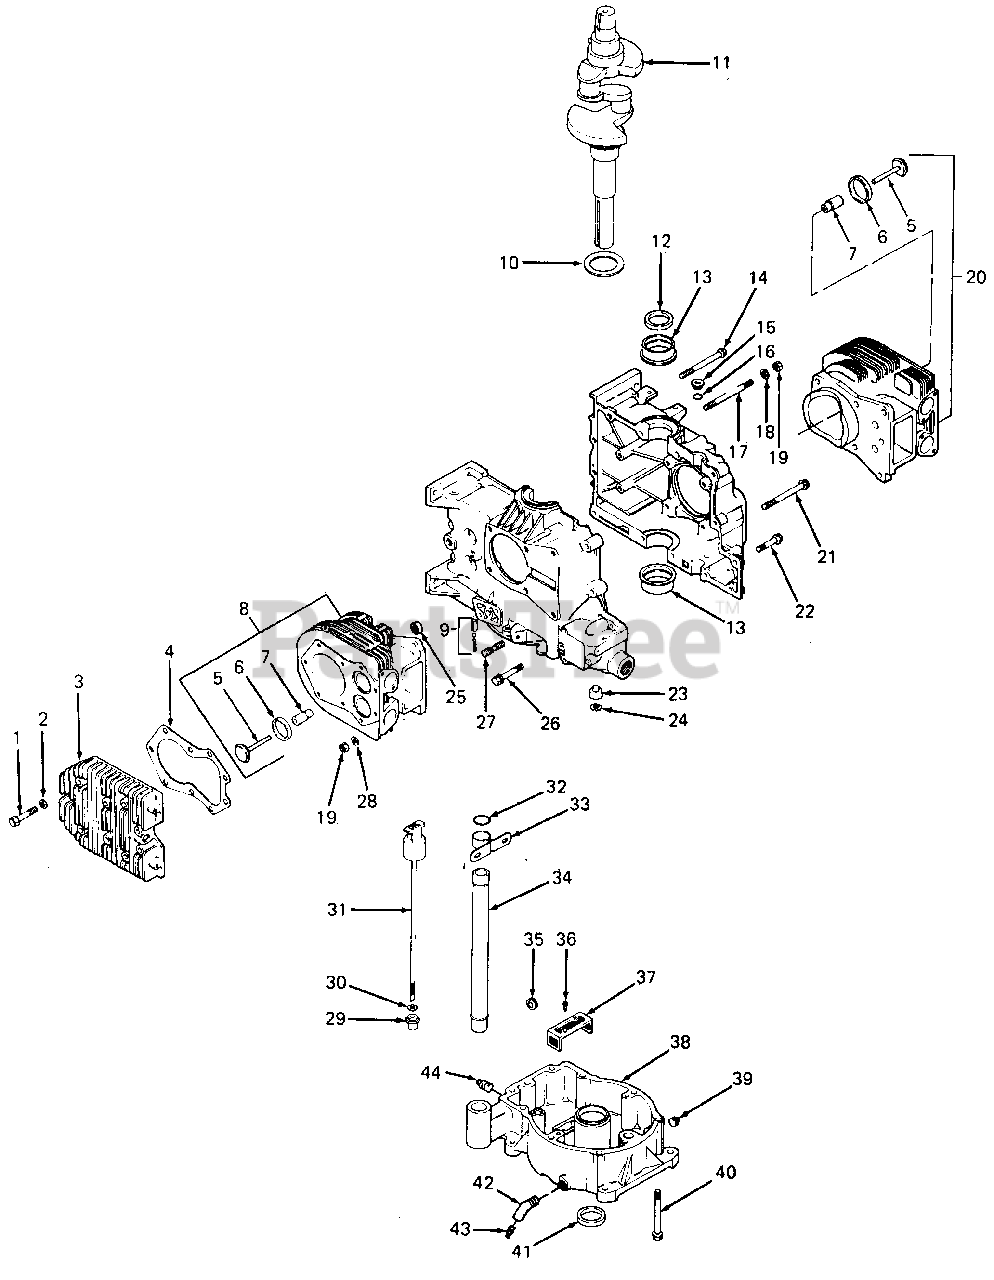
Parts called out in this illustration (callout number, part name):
1	Screw, Hex Hd, 5/16-18 X 1-1/2
2	Washer, Plain, 5/16
3	Head, Cylinder
4	Gasket, Cylinder Head
5	Valve, Exhaust
6	Insert, Valve Seat
7	Valve, Guide
8	Kit, #1 Cylinder Barrel
9	Oil Relief Kit
10	Washer, Thrust, .119/.122
11	Crankshaft, 3-5/32 X 1 in., Tapped PTO
12	Seal, Front Oil
13	Bearing, Sleeve, Std
14	Screw, Hex Flange, 5/16-18 X 3-1/2
15	Plug, 3/4 in. OD
17	Stud, 5/16-18 X 4-1/8
18	Washer, Plain
19	Nut, Hex, 5/16-18
20	Kit, #2 Cylinder Barrel
21	Screw, Hex Flange, 3/8-16 X 3-5/8
22	Screw, Hex Flange, 5/16-18 X 1-1/2
23	Shaft, Governor
24	Ring, Retaining
25	Bushing, Locating
26	Screw, Hex Flange, 5/16-18 X 2
27	Stud, Step, 5/16-18 X 3/4, 3/8-16 X 5/8, 2 in. Lg
28	Washer, Flat, 5/16
29	Seal, Rubber
30	Washer, Plain, 5/16
31	Dipstick, 13-1/2 in. Blade
33	Bracket, Oil Tube Support
34	Tube, Oil Fill, 11-7/8
35	Plug, Hex Ctsk, 3/4 NPTF
36	Screw, Hex Wash Hd, 10-32 X 7/16
37	Filter, Oil Pickup
38	Pan, Oil
39	Plug, Sq Solid Hd, 3/8 NPTF
40	Screw, Hex Wash Hd, 5/16-18 X 3-1/4
41	Seal, Rear Oil
42	Pipe, Oil Drain
43	Plug, Pipe, H-Hd Auto, 1/4-18 ZNP
44	Plug, Hex Ctsk, 1/4 NPTF
